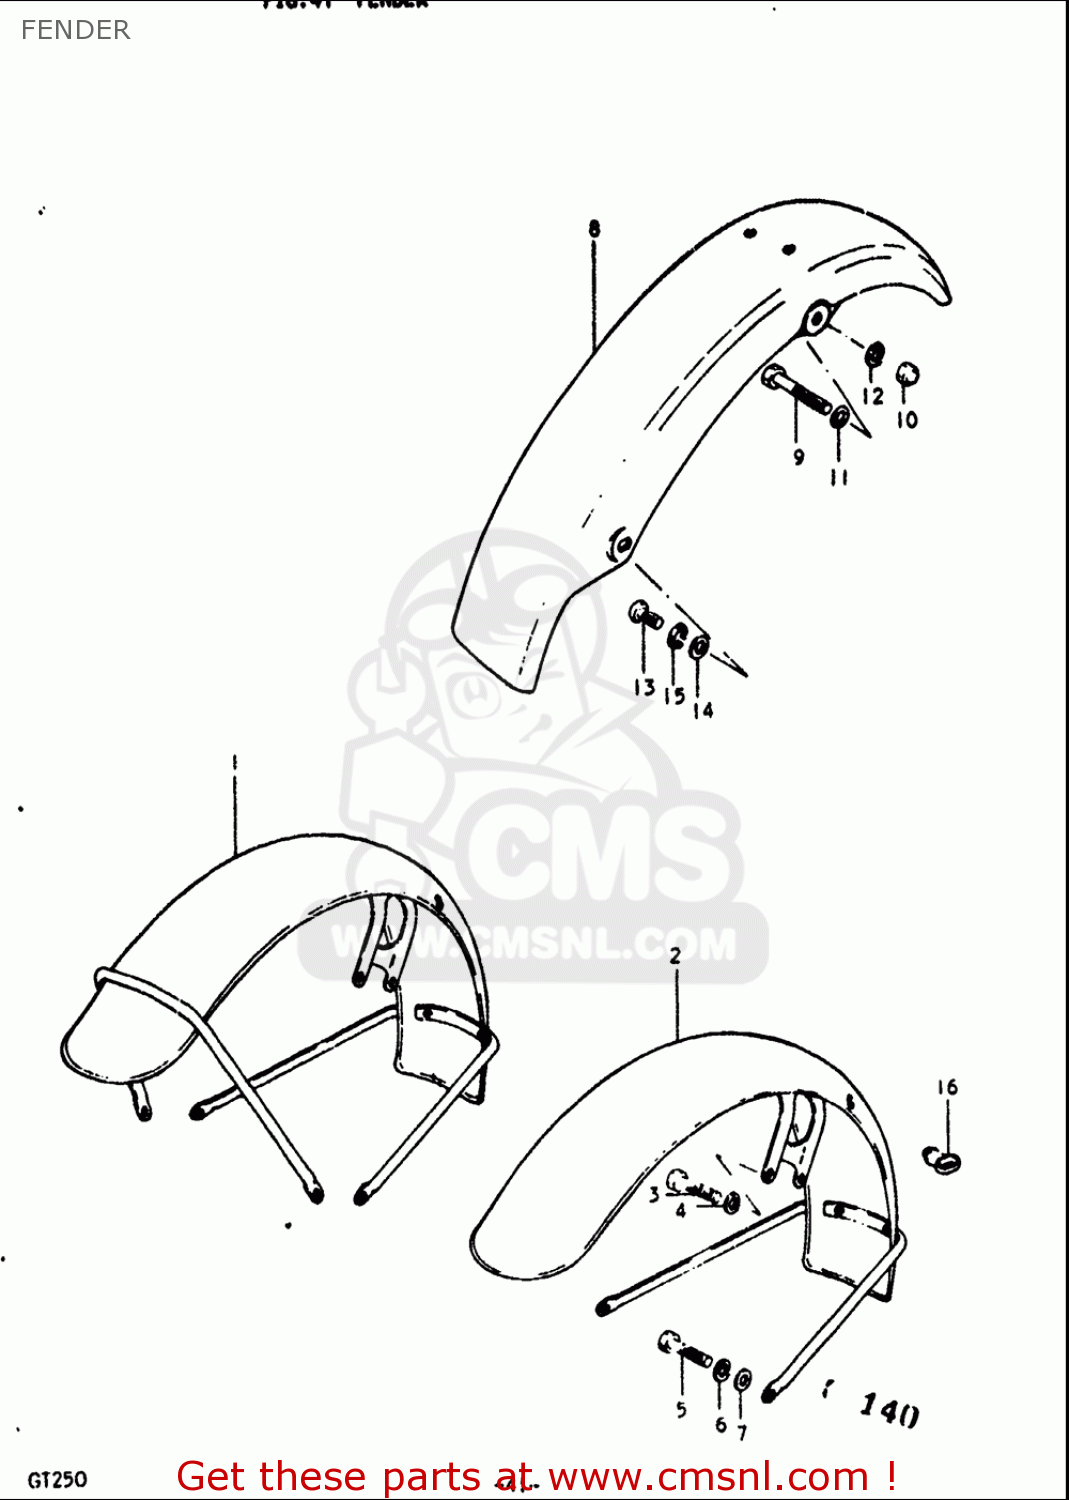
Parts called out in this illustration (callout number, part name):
3	BOLT
4	WASHER,LOCK
5	BOLT
6	WASHER,LOCK
7	WASHER
9	BOLT
10	NUT
11	WASHER
12	WASHER,LOCK
13	BOLT(8X14)
14	WASHER
15	WASHER,LOCK
16	GUIDE,CABLE
